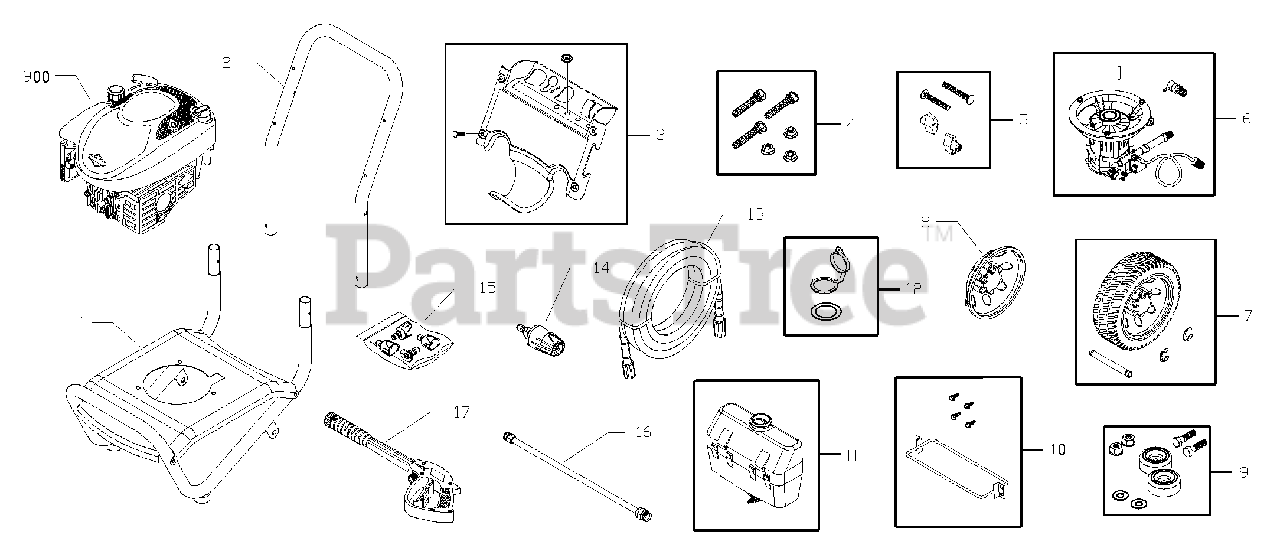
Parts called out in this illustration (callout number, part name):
2	HANDLE
3	ASSY, Billboard w/Clips
4	KIT, Pump Mounting Hardware
5	KIT, Handle Connector
6	ASSY, Pump
9	KIT, Vibration Mount
10	KIT, Wireform
11	ASSY, Tank, Chem
12	KIT, Cap, Chem Container
14	ASSY, Turbo Max
15	KIT, Nozzle
16	ASSY, Extension
17	GUN
900	ENGINE
